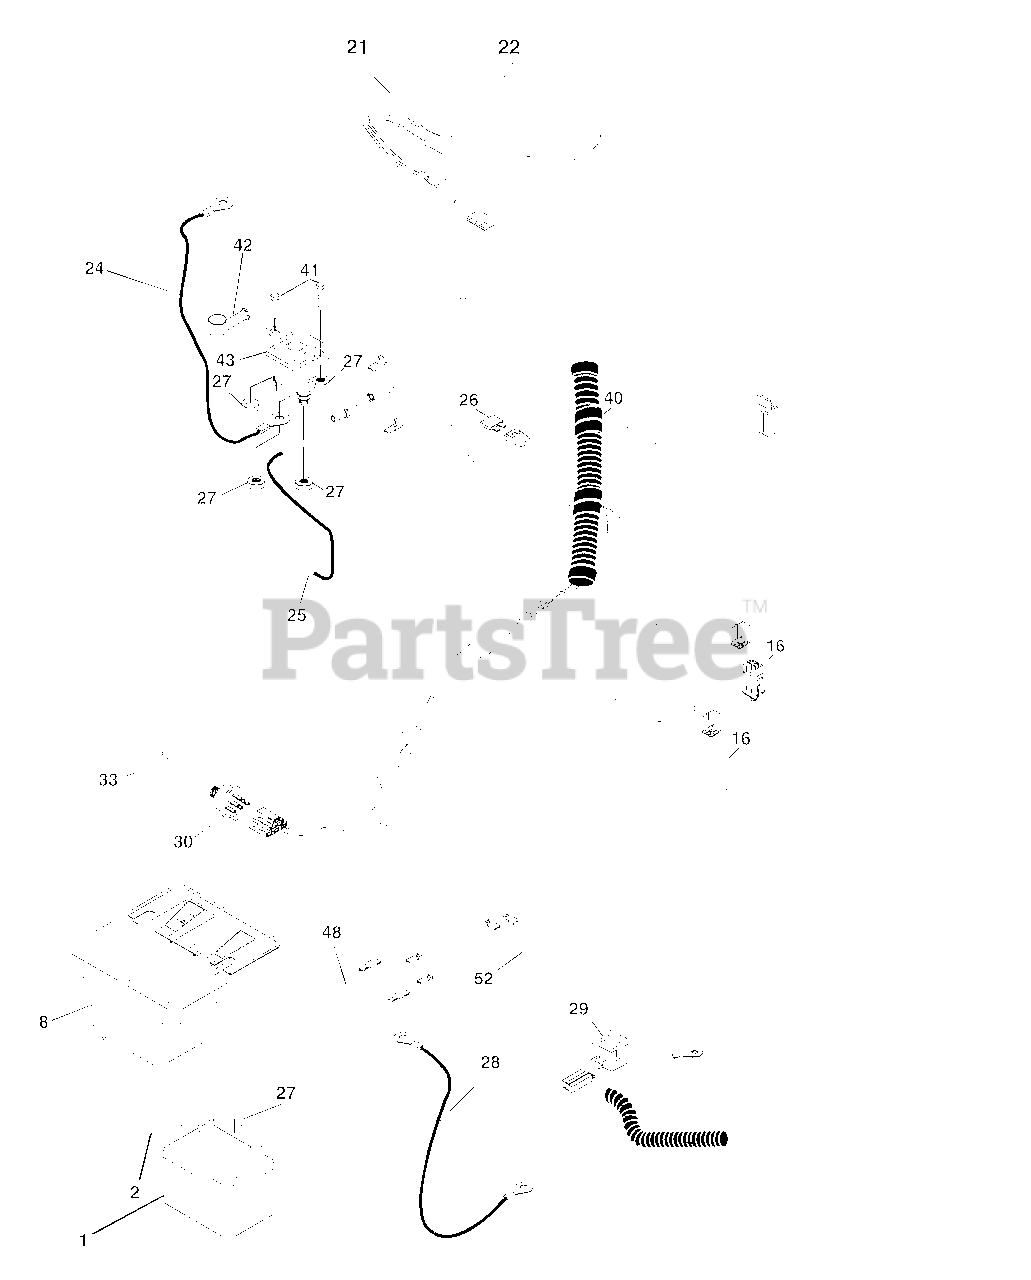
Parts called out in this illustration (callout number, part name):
1	Battery 12 Volt 25 Amp
2	Bolt Hex Hd 1/4-20unc X 3/4
8	Case Battery
16	Switch Interlock Push -In
21	Harness Asm Light W/4152J
22	Bulb Light #1156
24	Cable Battery 6 Ga 11" red
25	Cable Battery 6 Ga w/16 wire, red
26	Fuse 15 AMP
27	Nut Keps Hex 1/4-20 unc
28	Cable Ground 6 Ga 12" black
29	Switch Plunger Nc Gray
30	Switch Ign
33	Key Ign
40	Harness Ign
41	Bolt Blk Fin Hex 1/4-20 X 1/2
42	Cover Terminal Red
43	Solenoid
48	Adapter Ammeter Rectangular
52	Protection Wire Loop
